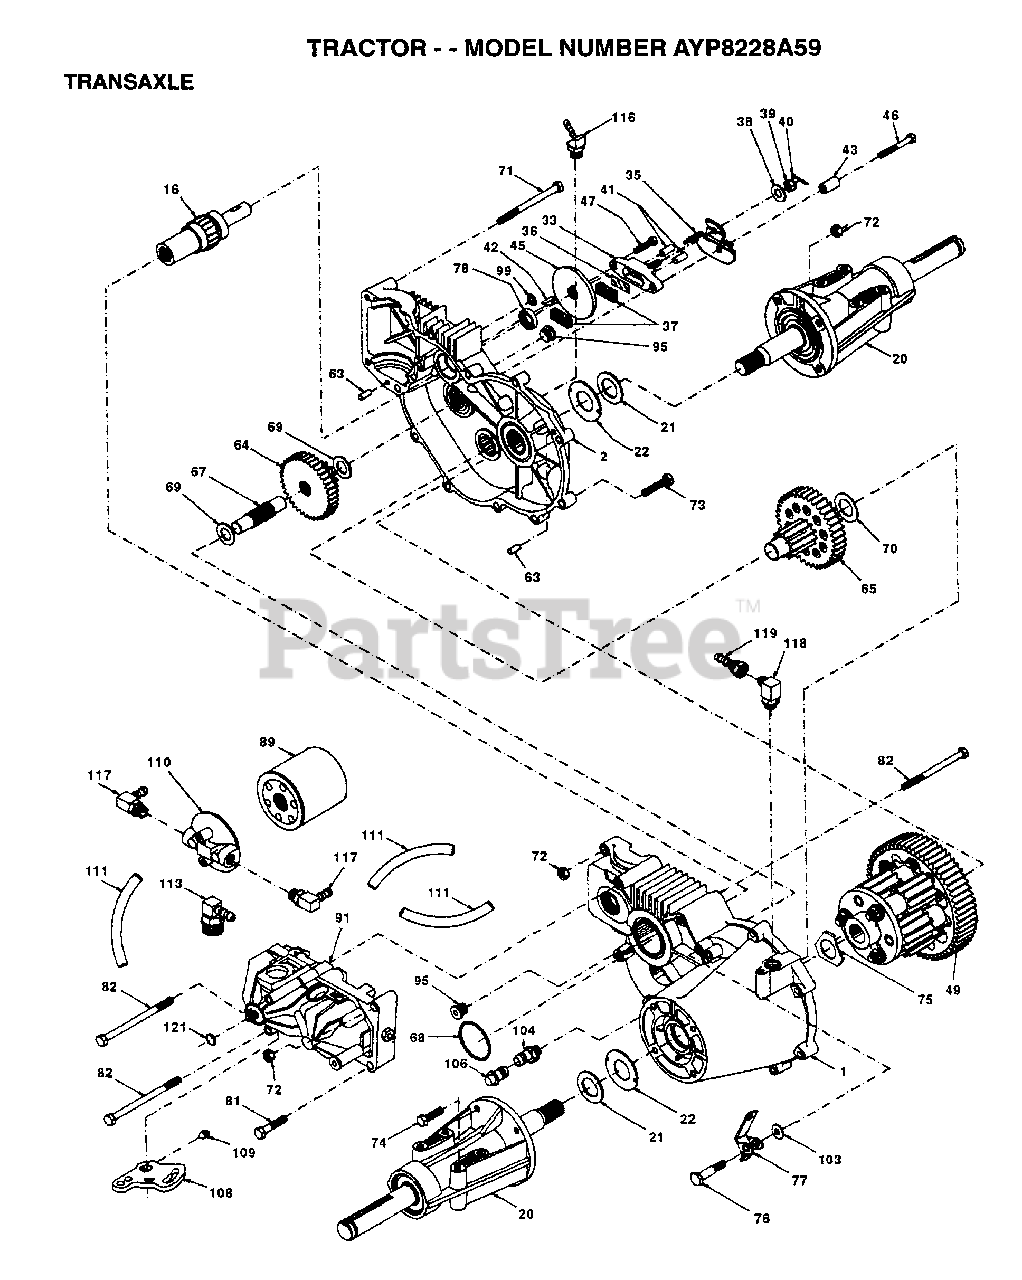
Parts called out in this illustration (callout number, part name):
1	HOUSING LH 70086
2	HOUSING RH 70088
16	SHAFT BRAKE 62877
20	AXLE MTG 70087
21	WASHER 44805
22	WASHER 44806
33	YOKE.BRAKE.62589
35	ARM BRAKE 50214
36	PUCK PLATE 44134
37	PUCK BRAKE 44132
38	WASHER HYD 44130
41	PIN BRAKE 44127
42	KEY HI PRO 44143
43	SPACER 50259
45	DISC BRAKE 44090
46	BOLT 1/4-20 44276
47	BOLT 1/4-20 44433
49	DIFFERENTIAL62834
63	PIN DOWL 44757
64	GEAR R14-38 44775
65	PINION DRIV 70051
67	SHAFT-44779
68	O RING 44781
69	WASHER 44795
70	WASHER 44794
71	BOLT 5/16 44827
72	NUT HXLK 43064
73	BOLT 5/16 44841
74	SCREW 5/16 45089
75	WASHER DIF 44880
76	BOLT SHOULD 44785
77	ARM FREEWHL 44786
78	SEAL.OIL.44761
81	BOLT 5/16 43084
82	BOLT 5/16 44820
89	FILTER SPIN 50037
95	PLUG.9005110-5600
103	WASHER.50169
104	CAP.VENT.70109
106	O-RING.ASM.70110
108	ARM.CONTROL.45007
109	SCREW.SET.50018.
110	FILTER.HEAD.50207
111	HOSE.5/16.50208.
113	FITTING.SAE.50210
116	FITTING.SAE.50213
117	FITTING.SAE.50249
118	FITTING.MAL.50251
119	FITTING.FEM.50250
121	RING.RET.2003016.
